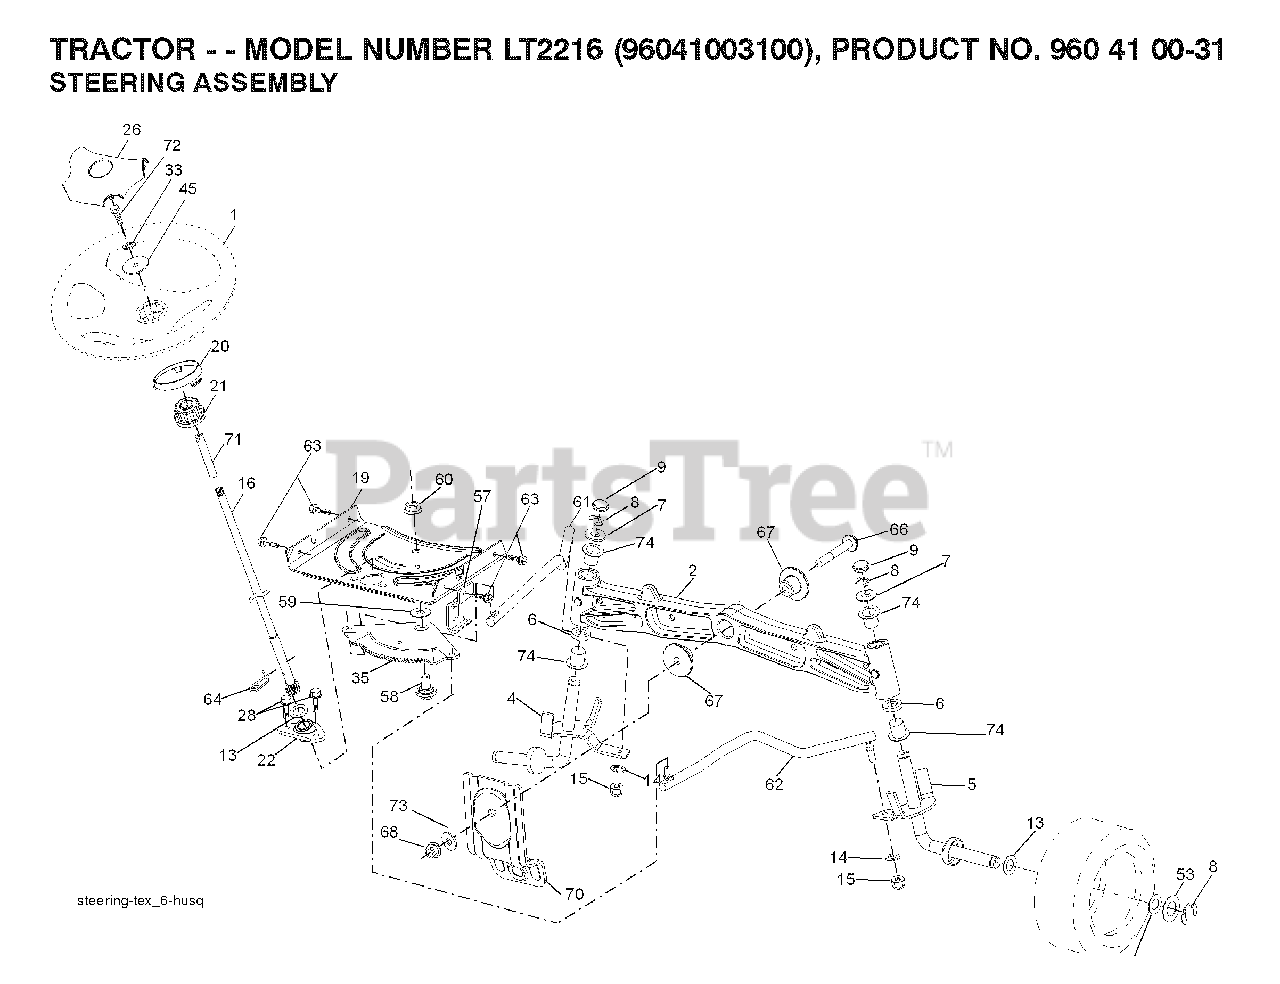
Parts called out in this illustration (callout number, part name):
2	AXLE.HALF.ASM.WELDED
4	SPINDLE.WELDED.LH.15"TEX
5	SPINDLE.WELDED.RH.15"T
8	RING CLIP
9	CAP.SPINDLE
14	WASHER, LOCK 3/8
15	NUT CROWNLOCK 3/8-24
16	SHAFT STEERING
19	PLATE.STEER.DDL.NLT/NG
20	BOOT STEERING BLACK
21	ADAPTER, WHEEL STNG..
22	BUSHING.ASM.STEERING.A
26	INSERT.CAP.STRG.WH.BLACK
28	SCREW, 3/8-16X3/4
33	LOCKWASHER
35	GEAR.SECTOR.PLATE.DDL.
45	WASHER.11/32
53	WASHER.HARDENED
57	BRACKET.UPSTOP.TEX
58	BOLT.SHOULDER.SECTOR.P
59	WASHER.THURST.SECTOR.S
60	NUT FLANGE LOCK 5/8-11
61	DRAGLINK.LH.BALLSTUD.D
62	DRAGLINK.RH.BALLSTUD.D
63	SCREW
64	RETAINER.CLIP.SPRING.S
66	BOLT HEX FGHD 7/16-14 X 3 SERR
67	BUSHING.PM.FRONT AXLE
68	NUT.LOCK.FLANGE.7/16
70	BRKT.DECK.SUSPENSION.F
71	SHAFT EXTENSION STEERING
72	BOLT YT
73	WASHER.1.5X.505X.118
74	BRNG T
